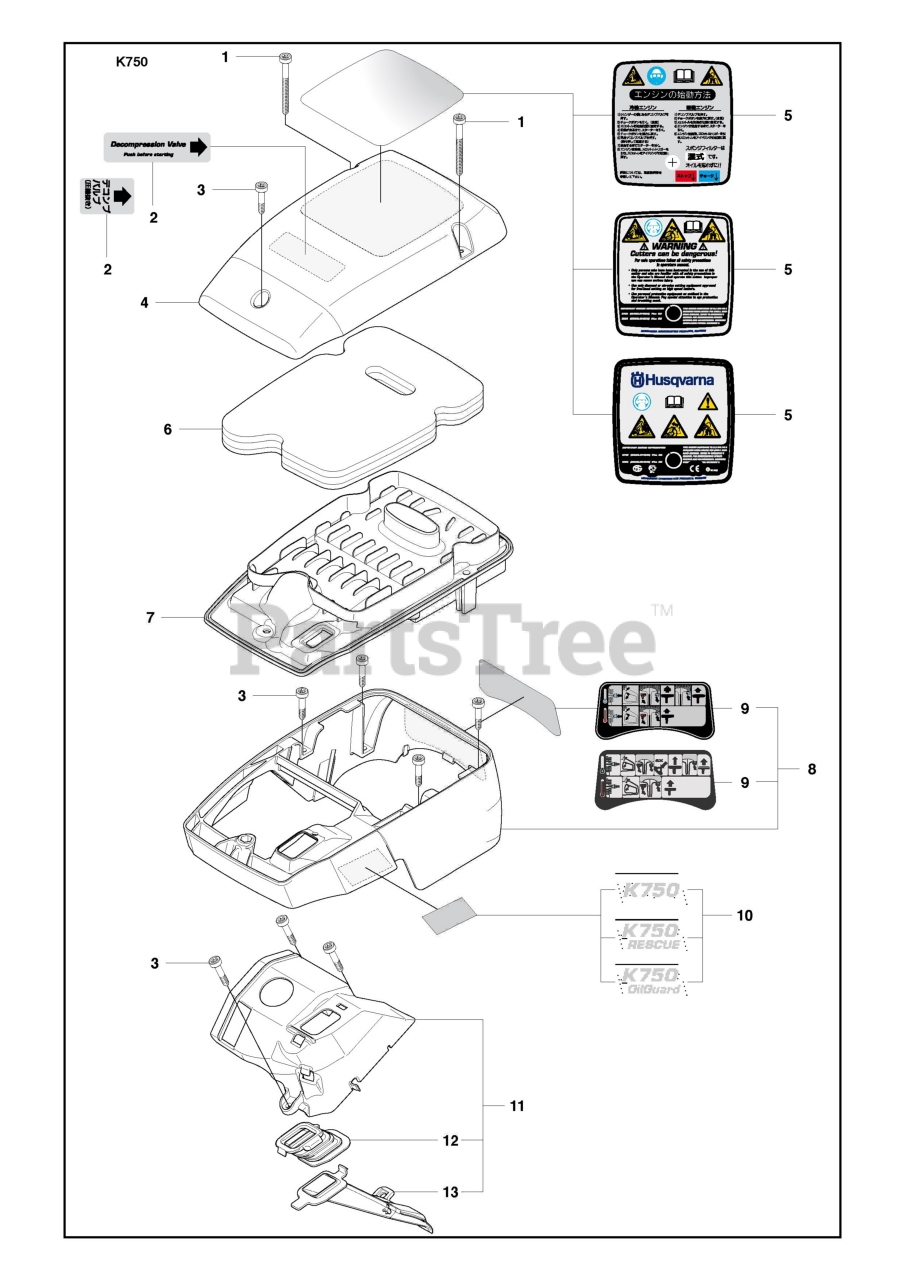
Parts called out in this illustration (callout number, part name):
2	Label
4	Filter Cover
5	Label
7	Filter Bottom
8	Cylinder Cover Assy
9	Label
10	Label
11	Cover
12	Bellows
13	Air Nozzle
